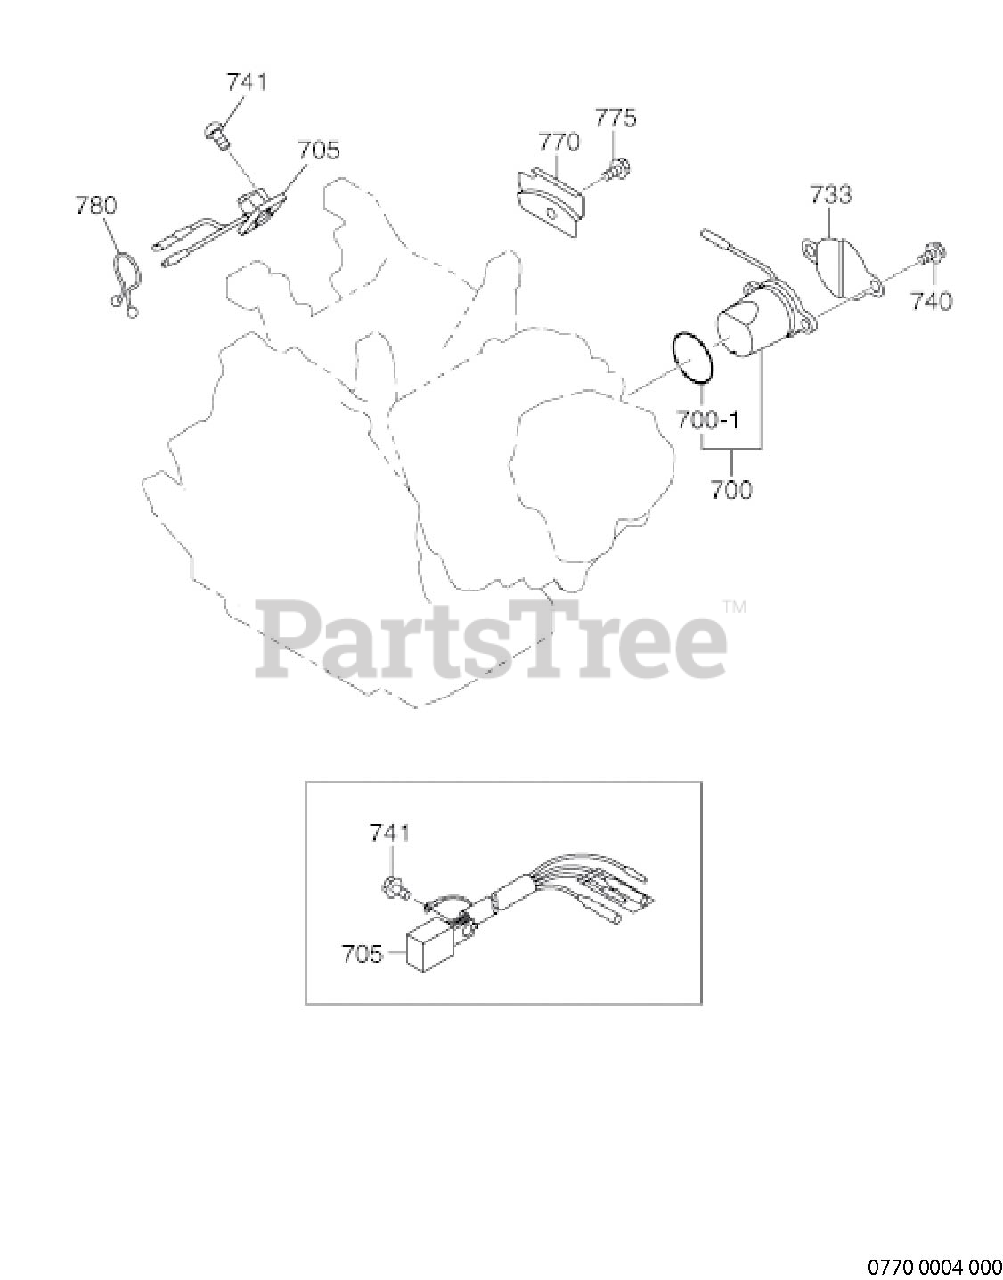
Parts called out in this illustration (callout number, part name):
733	SHIELD PLATE(O/S)
740	BOLT AND WASHER
741	BOLT AND WASHER AY
775	TAPPING BOLT
